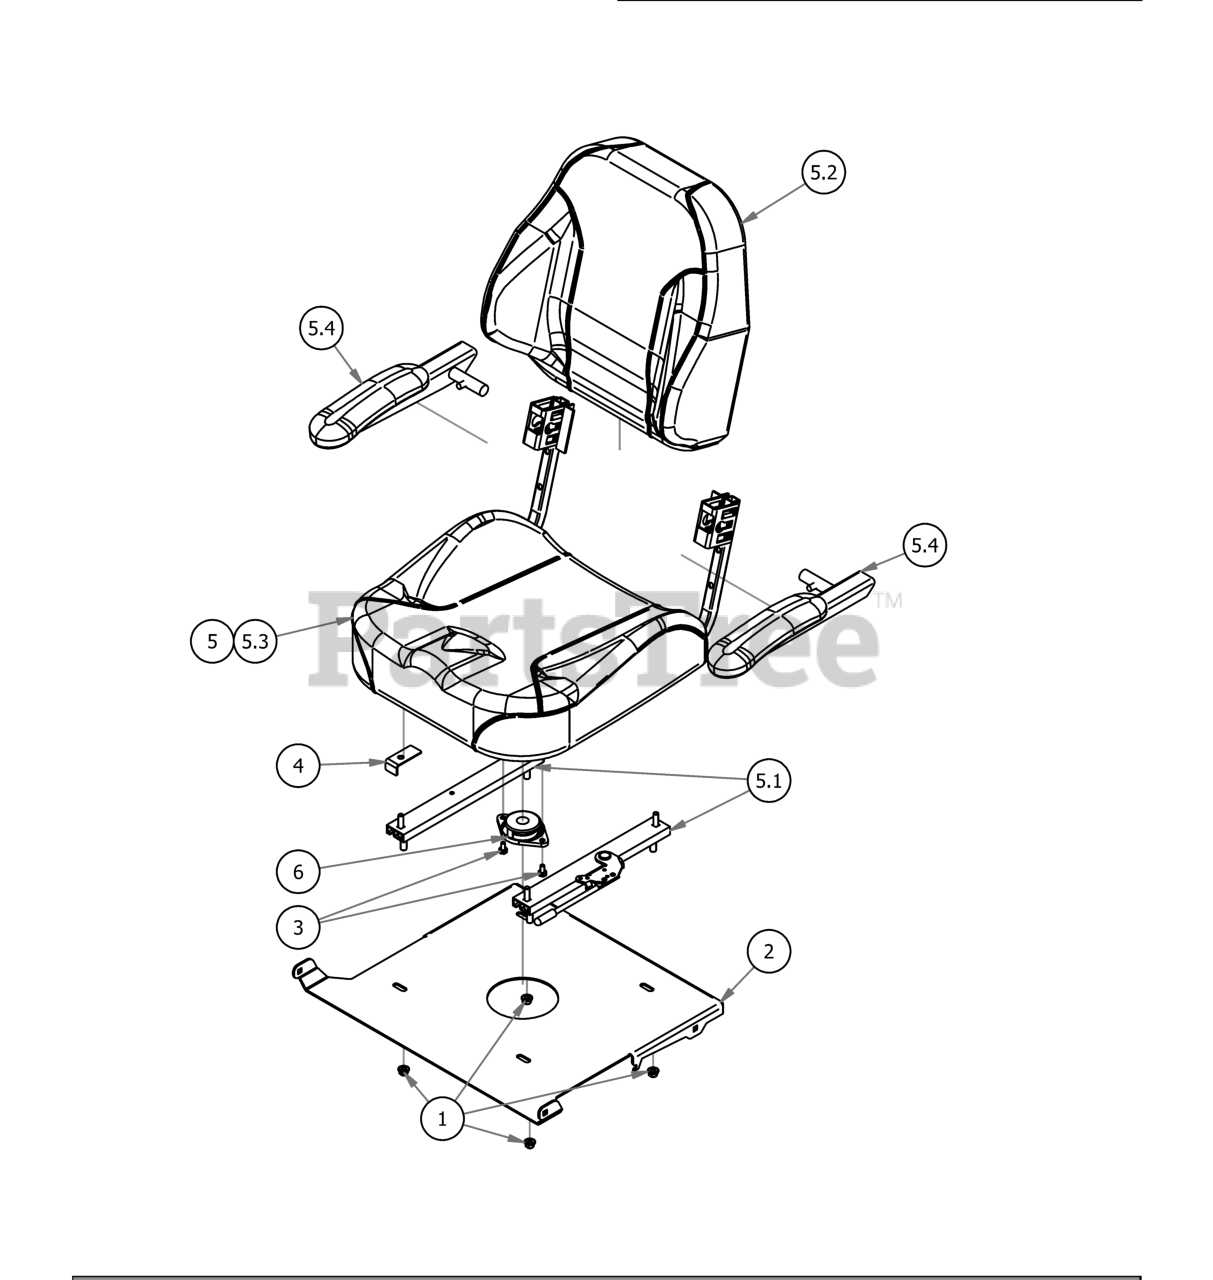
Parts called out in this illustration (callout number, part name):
1	5/16" Nylon Flange Nut
2	Seat Plate 2016
3	1/4-20x1/2 HWH Bolt Slot
4	MZ Seat Stop Bracket
5	2017 ZT Seat
5.1	Seat Rail Pair
5.2	Seat Back Cushion
5.3	Seat Bottom Cushion
5.4	Arm Rest (Pair)
6	Seat Safety Switch
